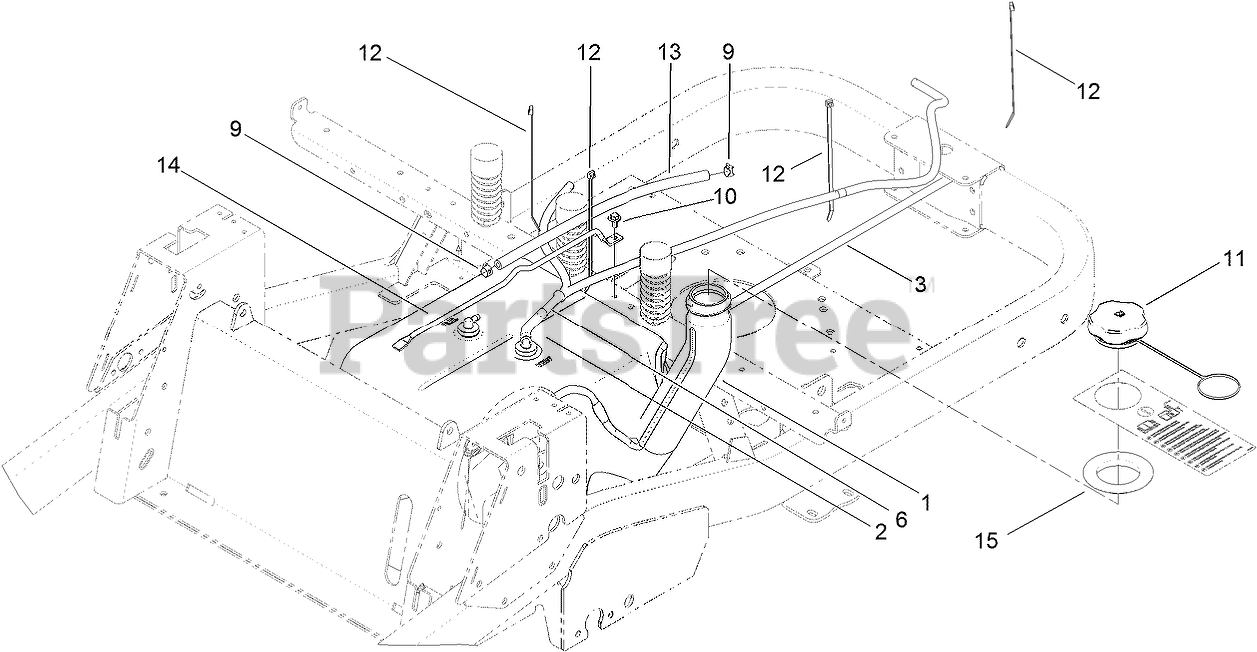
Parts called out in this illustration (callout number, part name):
1	FUEL TANK ASM
2	HOSE-FUEL
3	HOSE-FUEL
6	ADAPTER-ORIFICE
9	CLAMP-HOSE
10	SCREW-HHFTF
11	CAP-FUEL
12	TIE-CABLE
13	HOSE-FUEL
14	ROD-TANK, GAS
15	SEAL-TANK
